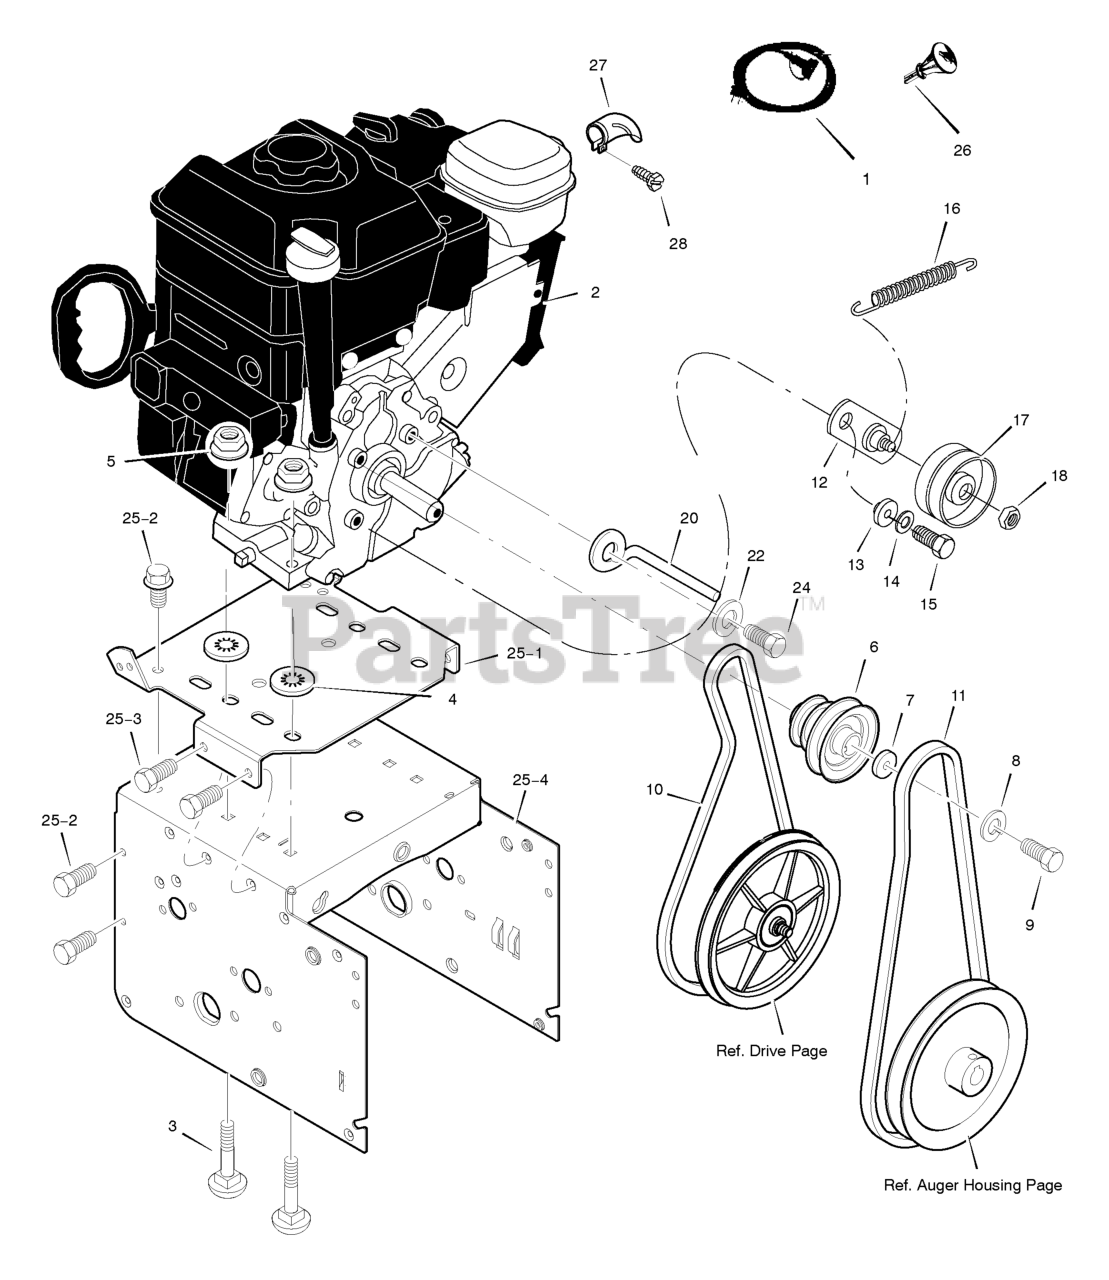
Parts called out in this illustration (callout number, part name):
1	CORD, Electric, 10FT. 110V
2	ENGINE
3	BOLT, CARRIAGE 5/16-18
4	RETAINER, PUSH
5	NUT 5/16-18
6	PULLEY, ENGINE
8	WASHER
9	SCREW, 3/8-24 x 1.00
10	BELT, V 3L
11	BELT, V 4L
12	BRACKET ASSEMBLY, IDLER
13	BUSHING, IDLER BRACKET
14	WASHER
15	SCREW 5/16-24 X 0.75
17	PULLEY, IDLER
18	NUT, JAM 3/8-16
20	GUIDE, ROD BELT
22	WASHER, SPTLK .31X.58X.08
24	SCREW, 5/16-24 x 0.75
25	FRAME ASSEMBLY
25-1	PLATE, ENGINE MOUNT
25-2	SCREW 1/4-20 X .63
25-3	SCREW 5/16-18 X .50
25-4	FRAME, MOTOR BOX
26	KEY, IGNITION
27	DEFLECTOR, Muffler
